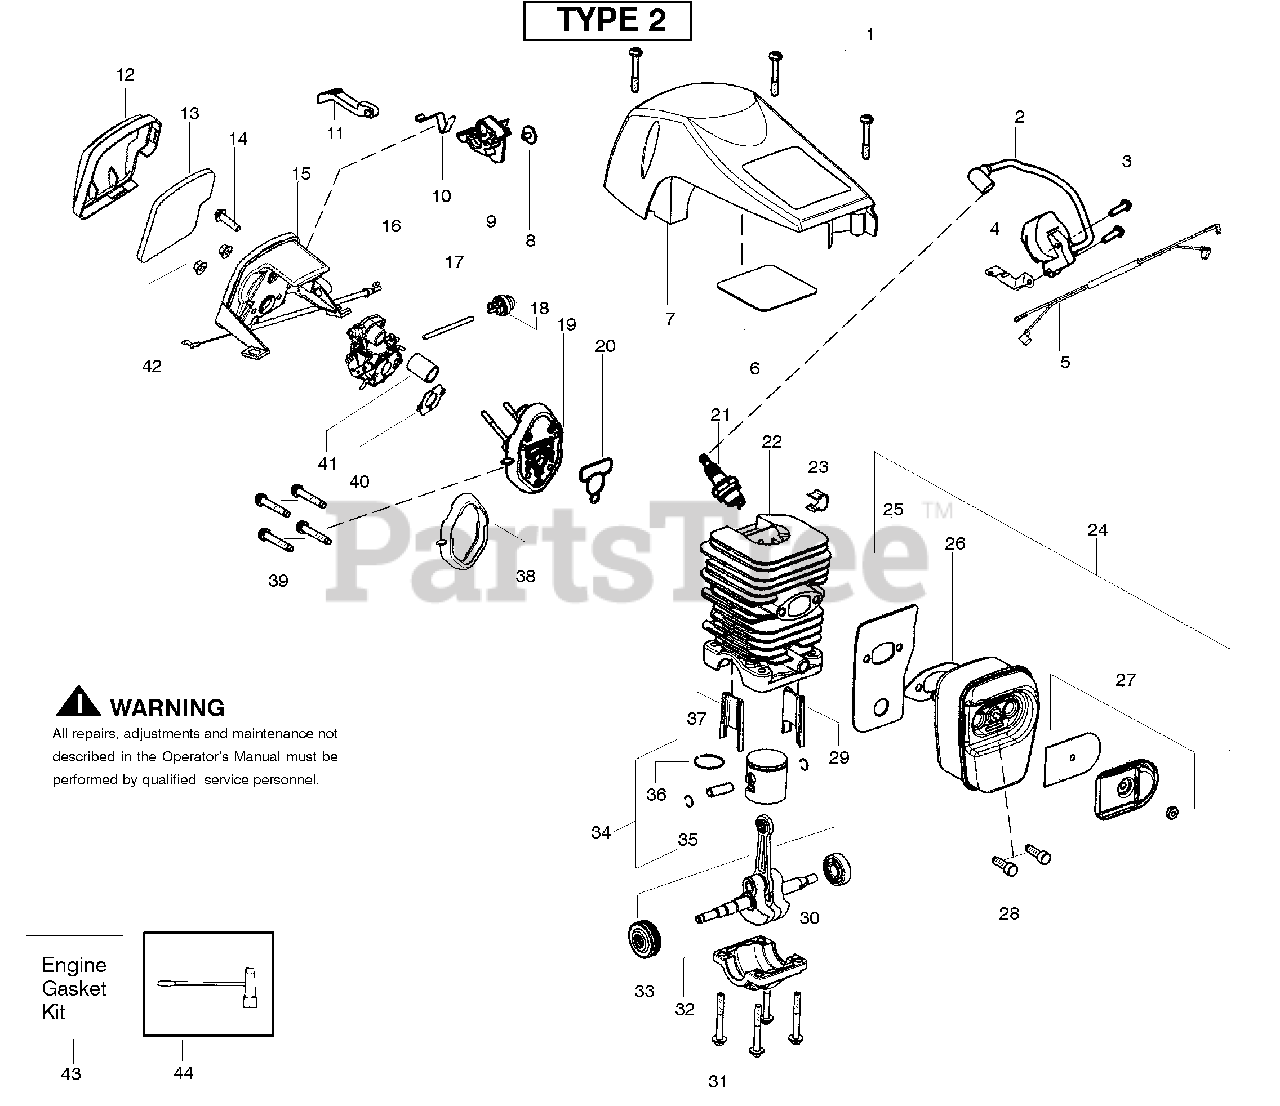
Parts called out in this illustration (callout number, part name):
2	Module-Ignition
5	Assy-Wire Harness
6	Reflector-Tape
7	Shield-Cylinder
9	Lever-Ignition Switch
10	Spring-Ignition Switch
12	Cover-Air Filter
15	Housing-Air Filter w/cable
16	Carburetor Zama W26
17	Kit-Fuel Line (Small)
18	Bulb-Purge "snap-in"
19	Kit-Carb. Adaptor
20	Gasket-cyl. o-ring (kit)
21	Accy-Spark Plug (RCJ-7Y)
22	Kit-Cylinder
23	Clip-High Tension Lead
24	Kit-Muffler
25	Backplate-Muffler
26	Gasket-Muffler (kit)
27	Kit-Spark Arrestor
29	Insert-Left (black) Cyl.
30	Assy-Crankshaft/Rod
32	Cap-Crankcase
33	Assy-Bearing/Seal
34	Kit-Piston
35	Retainer-Piston Pin
36	Ring-Piston
37	Insert-Right (gray)Cyl.
38	Seal-Adaptor (kit)
40	Gasket-Carb. (kit)
43	Kit-Gasket
44	Scrench
